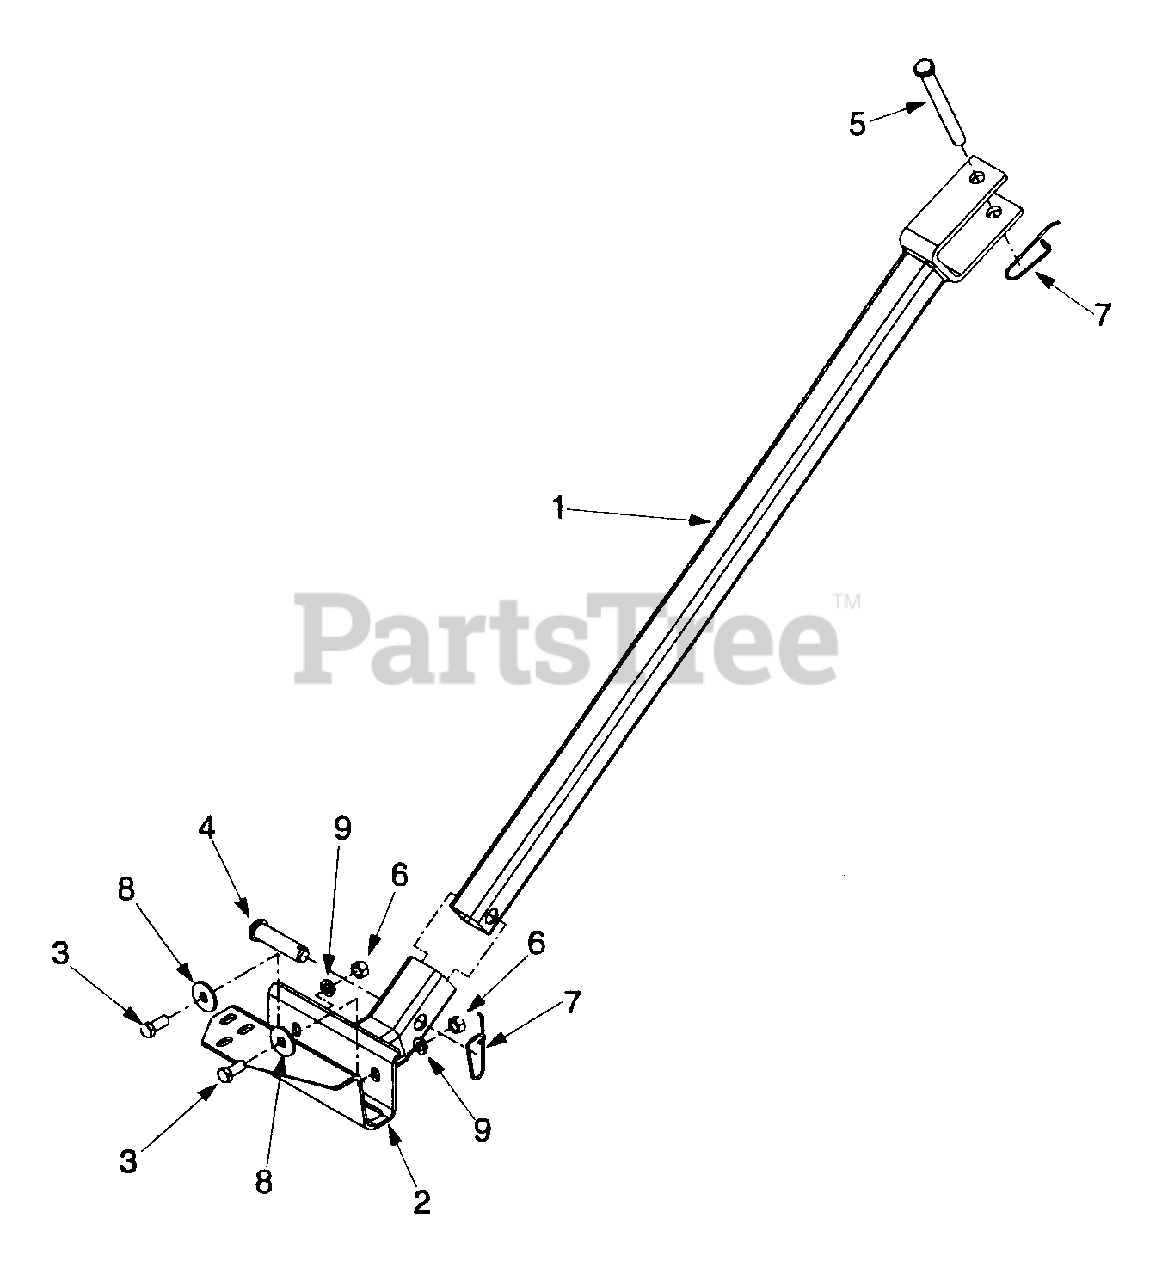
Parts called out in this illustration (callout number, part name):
3	Hex Cap Screw 3/8-16
4	Clevis Pin
5	Clevis Pin
6	Hex Nut 3/8-16
7	Spring Pin
8	Flat Washer .411 x 1.25 x 1.00
9	Lock Washer 3/8
